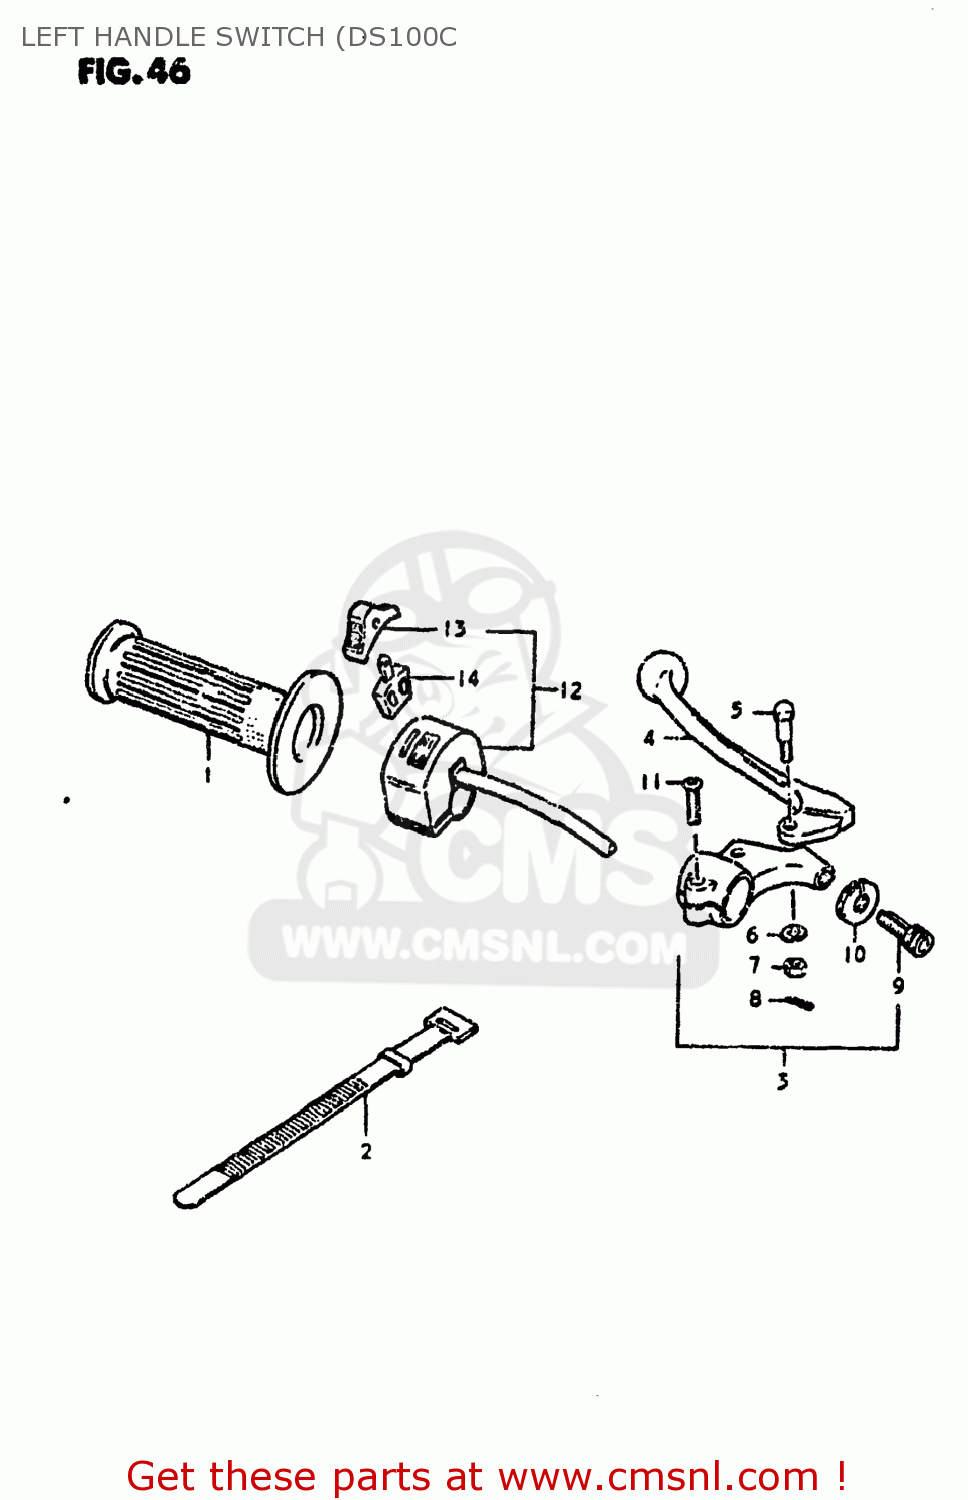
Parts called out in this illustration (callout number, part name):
1	GRIP,L
2	CLAMP(L:120)
3	LEVER ASSY,CLUTCH
4	LEVER,CLUTCH
5	BOLT,LEVER
6	LOCK WASHER
7	NUT 6MM
8	COTTER PIN
9	ADJUSTER,CABLE
10	NUT,CABLE ADJUSTER
11	SCREW
12	SWITCH,DIMMER
13	KNOB,HANDLE SWITCH
14	BLOCK,LIGHTING/DIMMER
